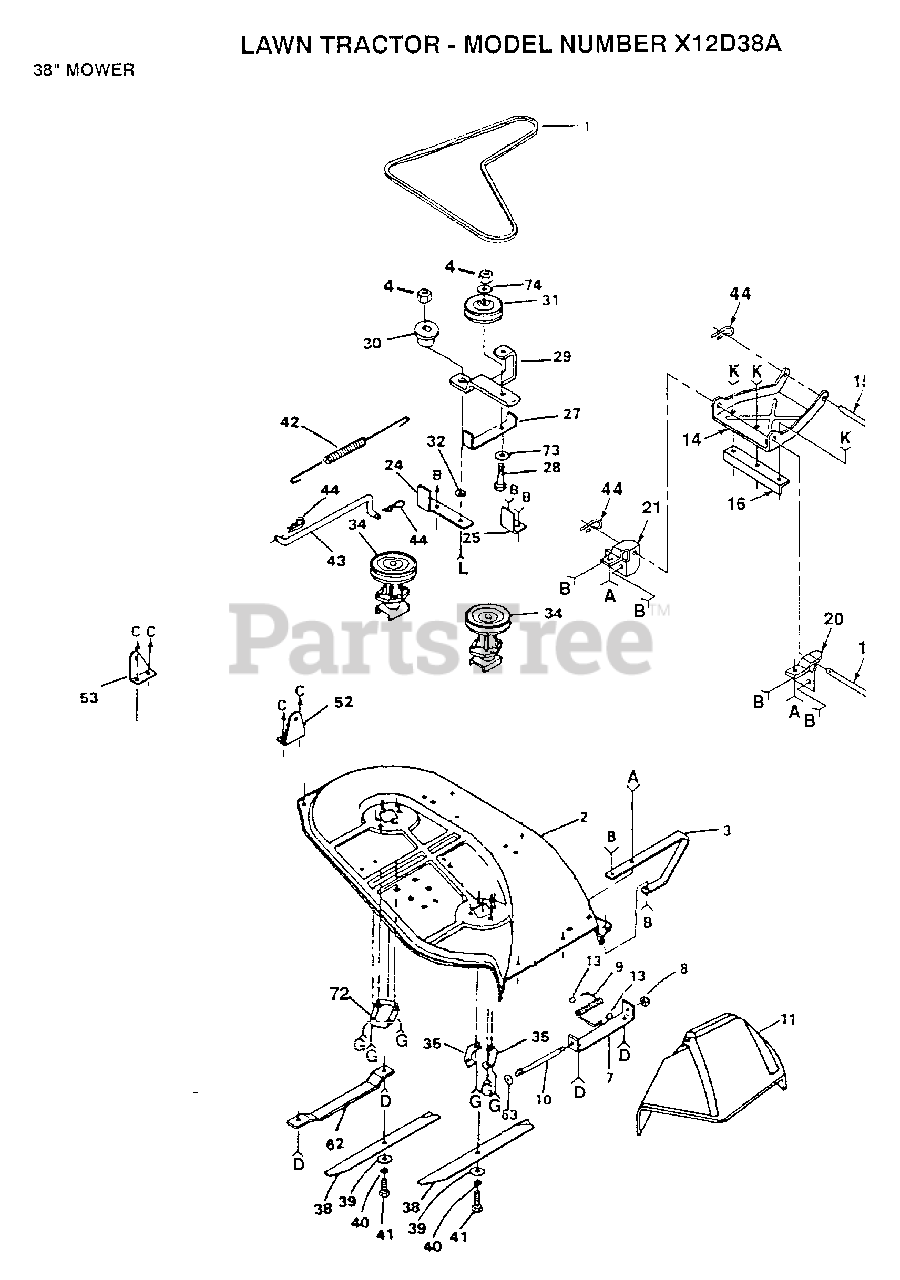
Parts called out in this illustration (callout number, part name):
1	BELT-V.79.1.MWR
8	NUT PUSH M
10	ROD-HINGE T
11	DEFLECTOR-SHLD T
13	CAP-SLEEVE LT
14	LINK.PARALLEL
15	"ROD, FRT. PARAL T"
16	LINK STOP
20	BRACKET RH LT
21	BRACKET LH T
24	SUPPORT ARM T
25	STOP T
28	BOLT
30	SPACER RETAINER
32	"WASHER, WEAR LT"
34	"JACKSHAFT.38""LT"
35	SUPPORT PLATE LT
38	"BLADE.38"" HI-LI"
39	WASHER
41	BOLT.3/8-24X1-1/2
42	"SPRING.EXT.8.5"""
44	SPRING.RETAINER
52	"BRKT,SUSP RH T"
53	"BRKT,SUSP REAR LH"
62	RUNNER-LH M
63	WASHER
72	SUPPORT T
73	WASHER
